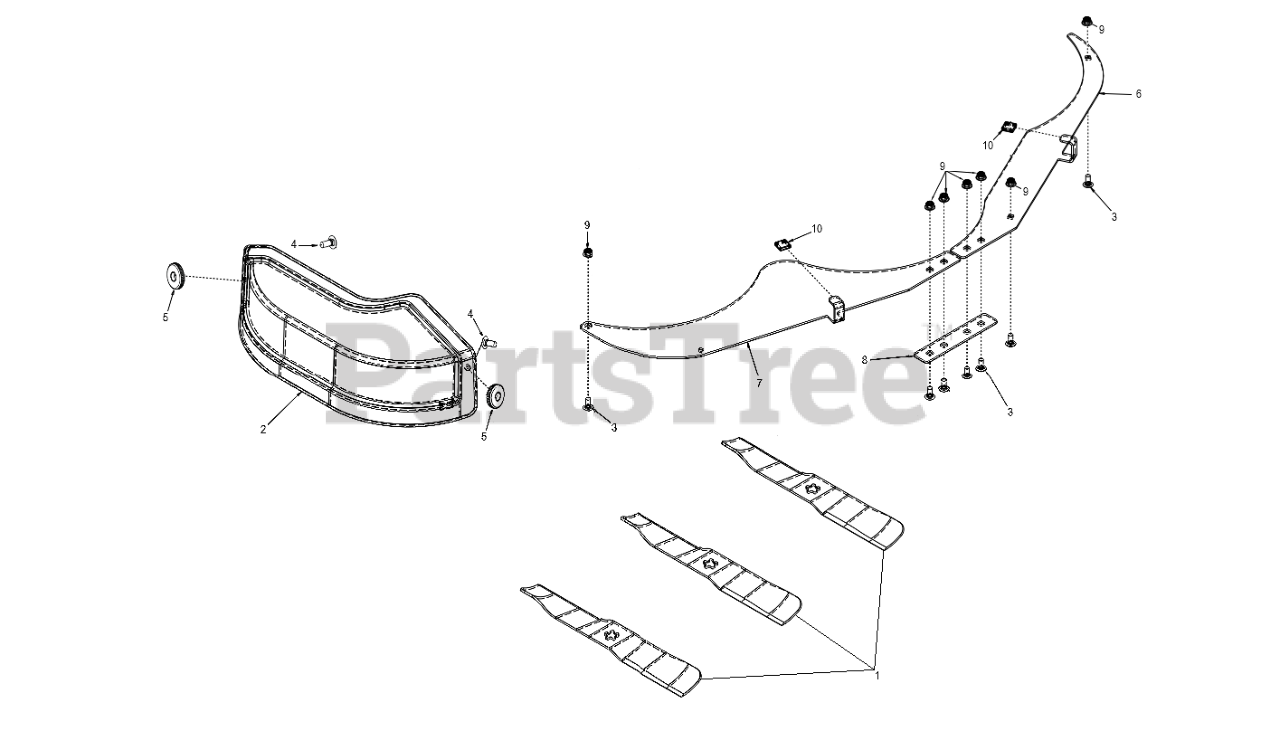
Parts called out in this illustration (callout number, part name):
1	BLADE..CLRCUT.RESD.MULCH.BLK
1	BLADE.48.CLRCUT.COMM.MULCH.BLK
2	COVER.48".CLEARCUT.MULCH.MS428
3	GSPW Bolts
5	NUT.KNOB.WINGNUT
8	PLATE.MATING.CNTMNT.48CC.MS431
9	NUT HEXAGON FLANGE 5/16-18 ST
